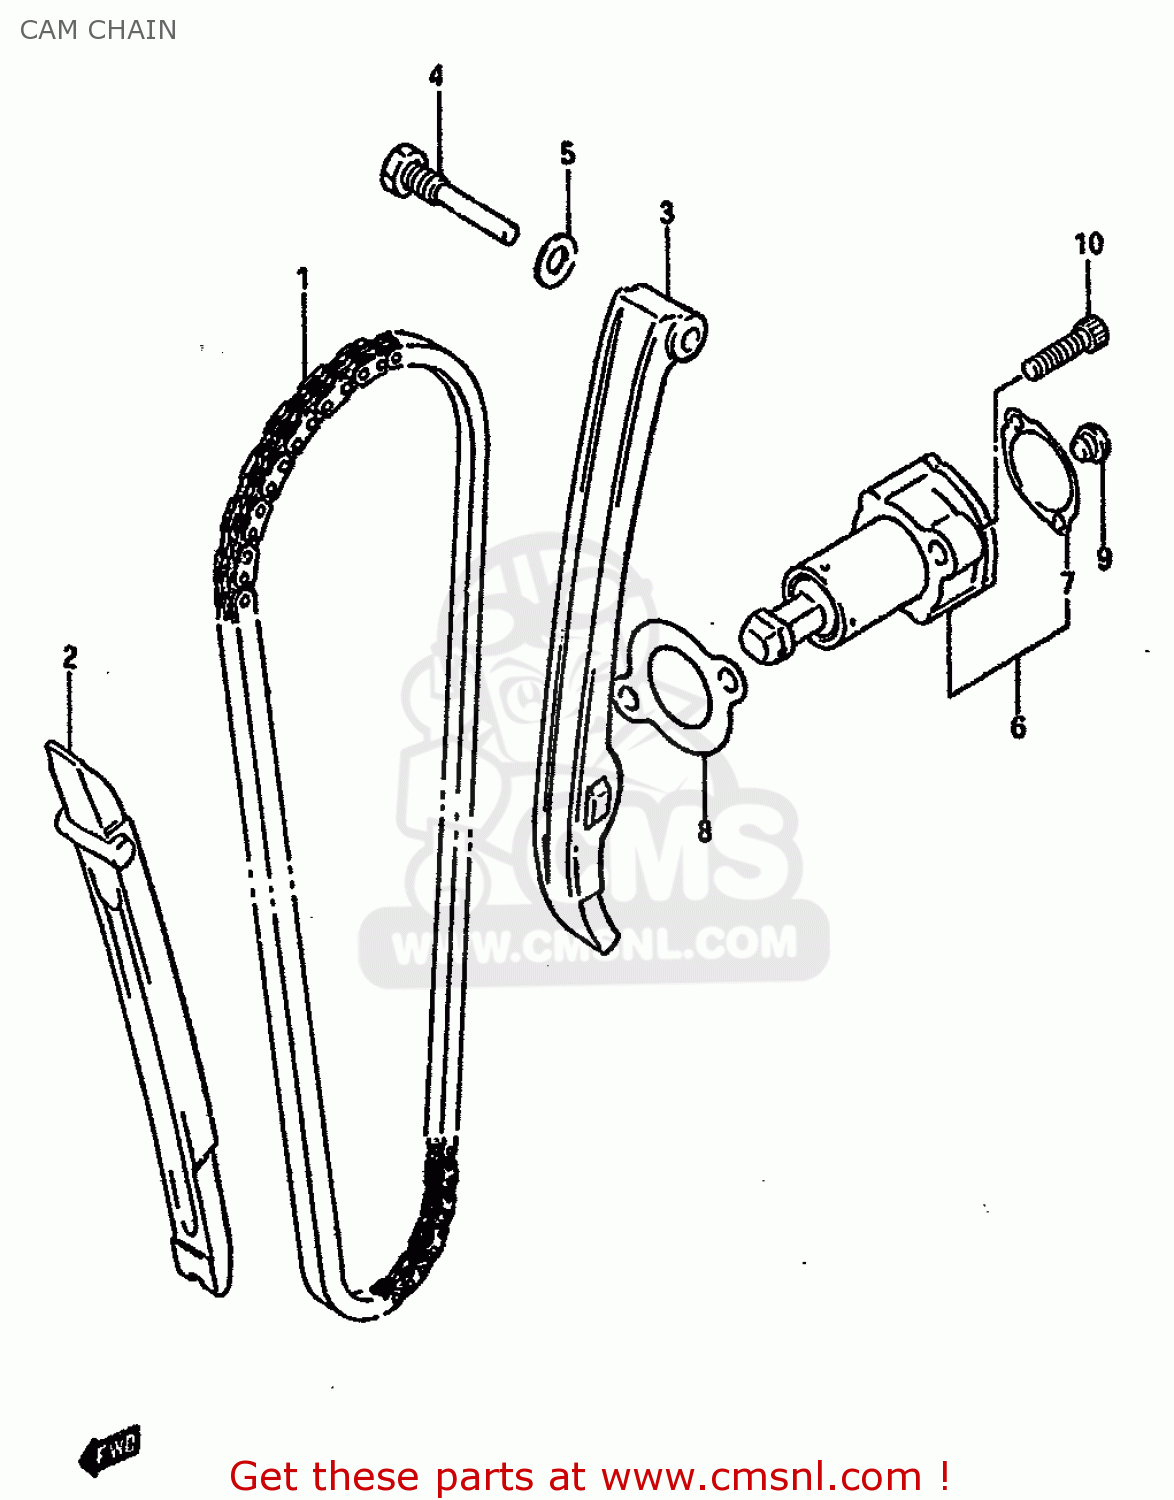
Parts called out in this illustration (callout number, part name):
1	CHAIN,CAMSHAFT DRIVE
2	GUIDE,CAM CHAIN
3	TENSIONER,CAM CHAIN
4	BOLT,CAM CHAIN TENSIONER
5	GASKET 8.2X14X1 (NAS)
6	ADJUSTER ASSEMBLY,TENSIONER
7	GASKET,ADJUSTER CAP (MCA)
8	GASKET,TENSIONER ADJUSTER
9	PLUG,ADJUSTER
10	BOLT
